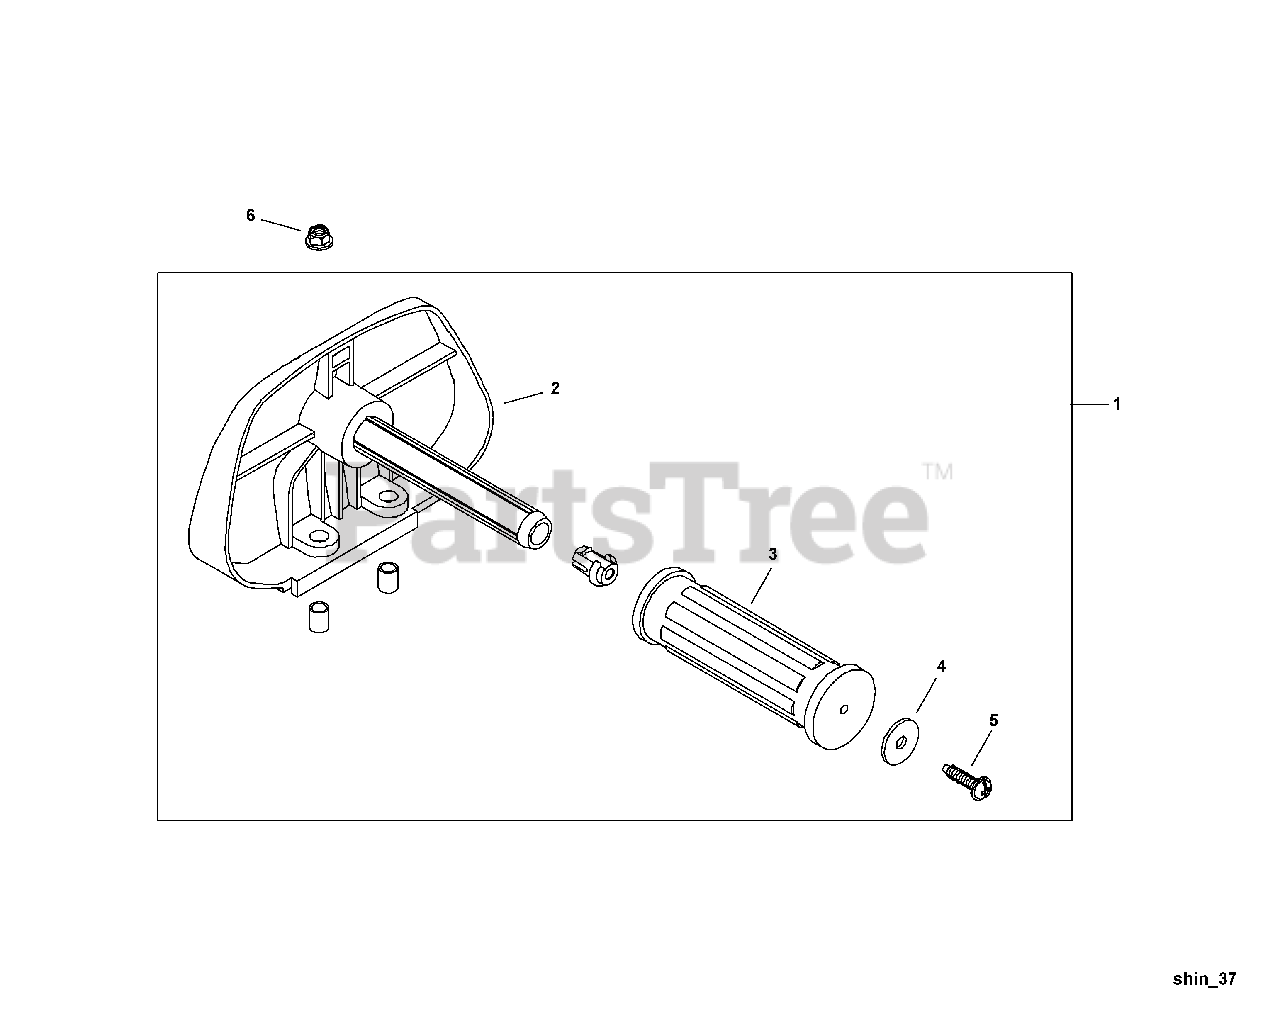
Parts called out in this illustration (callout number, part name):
1	HANDLE ASSY - FRONT
2	HANDLE - FRONT
4	WASHER - 5
5	SCREW - 5X20
6	NUT - 5
